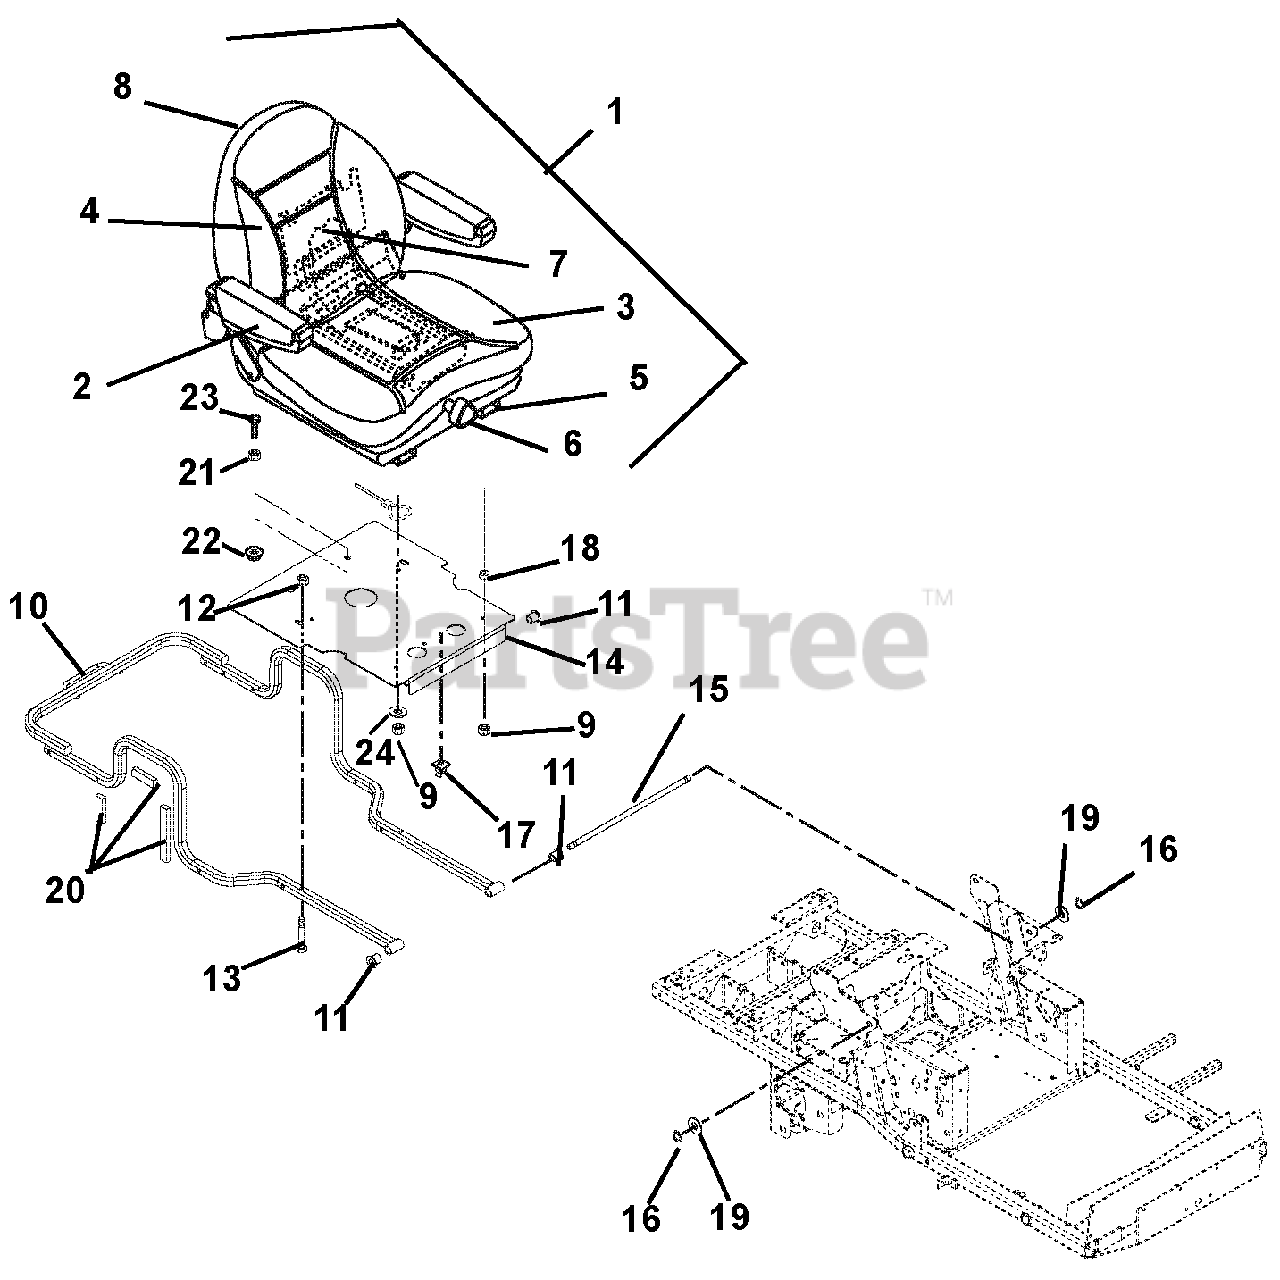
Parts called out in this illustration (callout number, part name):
1	SEAT - SUSPENSION - LIGHT GRAY
2	KIT,ARMREST PAD ONLY 1 PER KIT
3	KIT-SEAT CUSHION-LIGHT GRAY
4	KIT-BACK CUSHION-LIGHT GRAY
5	KIT-SEAT SLIDE
6	KIT-SEAT KNOB
7	KIT-SPRING AND SADDLE
8	KIT-SEAT BACK PANEL
9	@NUT-LK-TOP-FLG .31-18 YWZC
10	WMT, HOOD FRAME
11	BSHG-FLG .515X.750X.745X1.00NY
12	@NUT-LK-TOP-FLG .38-16 YWZC
13	BLT, .38-16X1.50 RIB NECK YWZC
14	WMT, SEAT PIVOT MOUNT
15	ROD - SEAT FRAME PIVOT
16	RG-RTNG-EXT .500X.050 (SNAP)
17	CLIP-.38
18	BSHG-SLV .377X.624X.235
19	@WSHR-FL-STL.531X1.06X.095YWZC
20	VHB TAPE 4941F
21	@NUT-HEX .50-13 YWZC
22	@NUT-LK-TOP-FLG .50-13 YWZC
23	@BLT-HEX .50-13X1.50 GR5 YWZC
24	WSHR-FL-STL .344X1.125X.135
